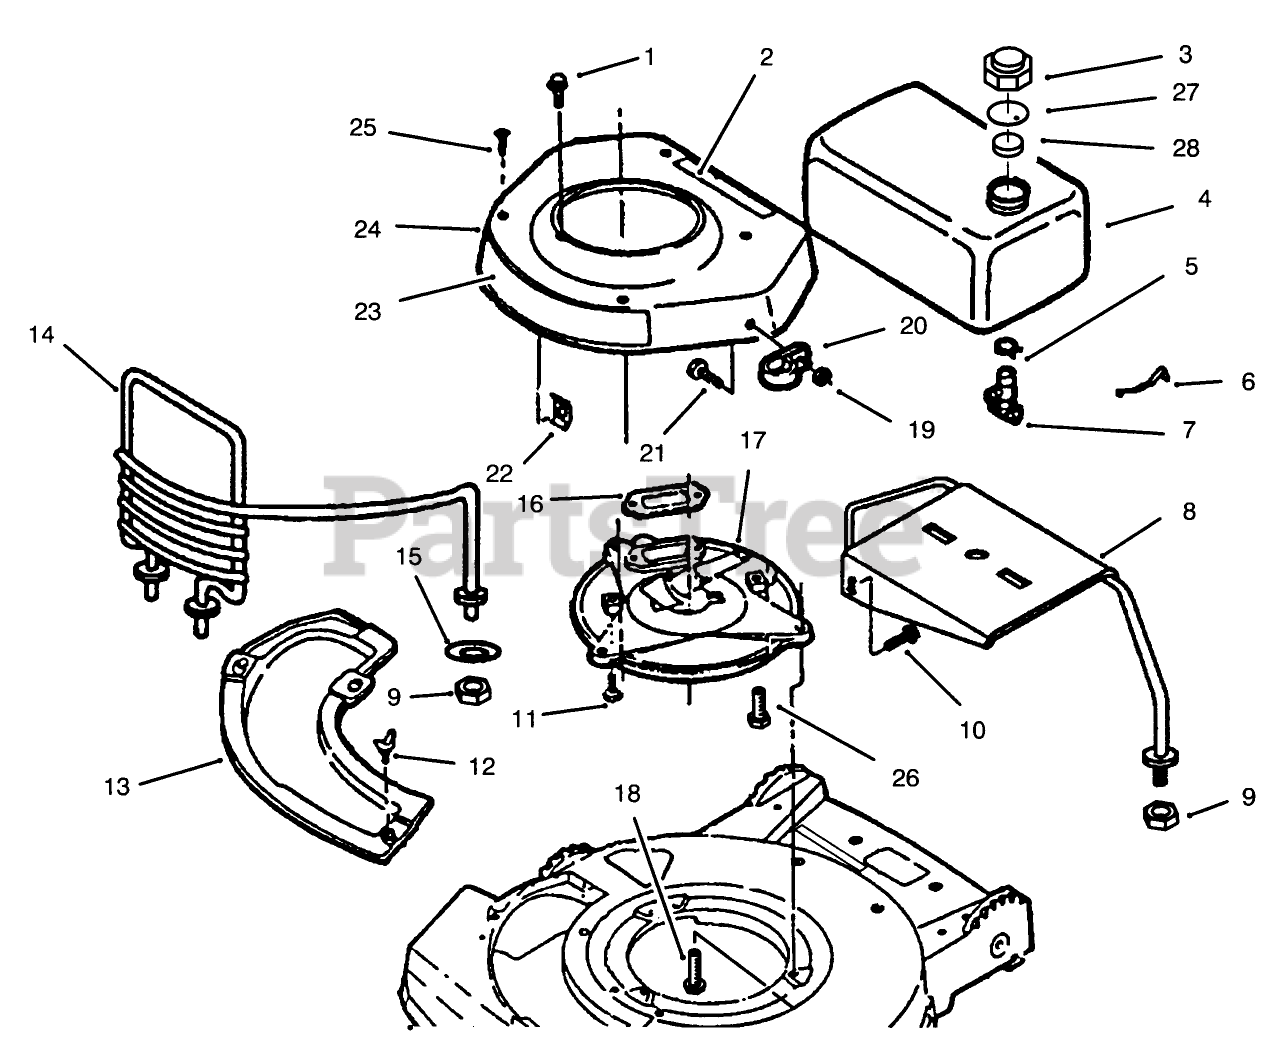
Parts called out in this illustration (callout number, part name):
1	SCREW SEMS SM
3	FUEL CAP & INSERT
4	TANK - FUEL
5	CLAMP - HOSE S
7	VALVE&SCREEN SM
9	NUT-LOCK, NI
11	SCREW V
16	GASKET-EXH. VF
17	MUFFLER PLATE F
19	NUT-LOCK, NI
21	SCREW-HWH
22	PUSHNUT F
25	SCREW - SELF TAPPING
26	SCREW-SEMS F
27	BAFFLE - FOAM SM
28	SCREW-SEMS F
